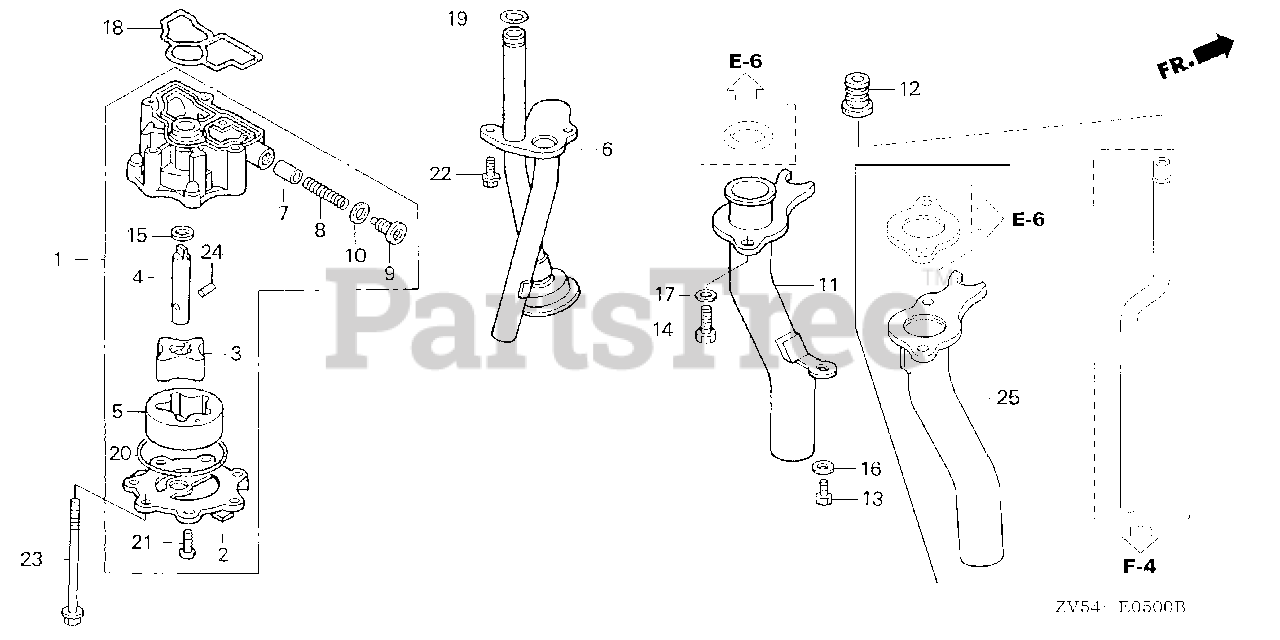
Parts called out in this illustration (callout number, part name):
1	PUMP ASSY., OIL
2	COVER, OIL PUMP
3	ROTOR (INNER)
4	SHAFT, OIL PUMP
5	ROTOR A (OUTER)
6	STRAINER, OIL
7	VALVE, RELIEF
8	SPRING, RELIEF VALVE
9	BOLT, SEALING (14MM)
10	WASHER, SEALING (14MM)
12	GROMMET, WATER TUBE
14	BOLT, HEX. (8X25)
15	WASHER, THRUST (12MM)
17	WASHER, PLAIN (8MM)
18	O-RING, PUMP COVER
19	O-RING (13.8X2.5)
20	O-RING (54X2.4) (ARAI)
21	SCREW, PAN (6X16)
22	BOLT, FLANGE (6X16)
23	BOLT, FLANGE (6X55)
24	ROLLER (5X17.8)
